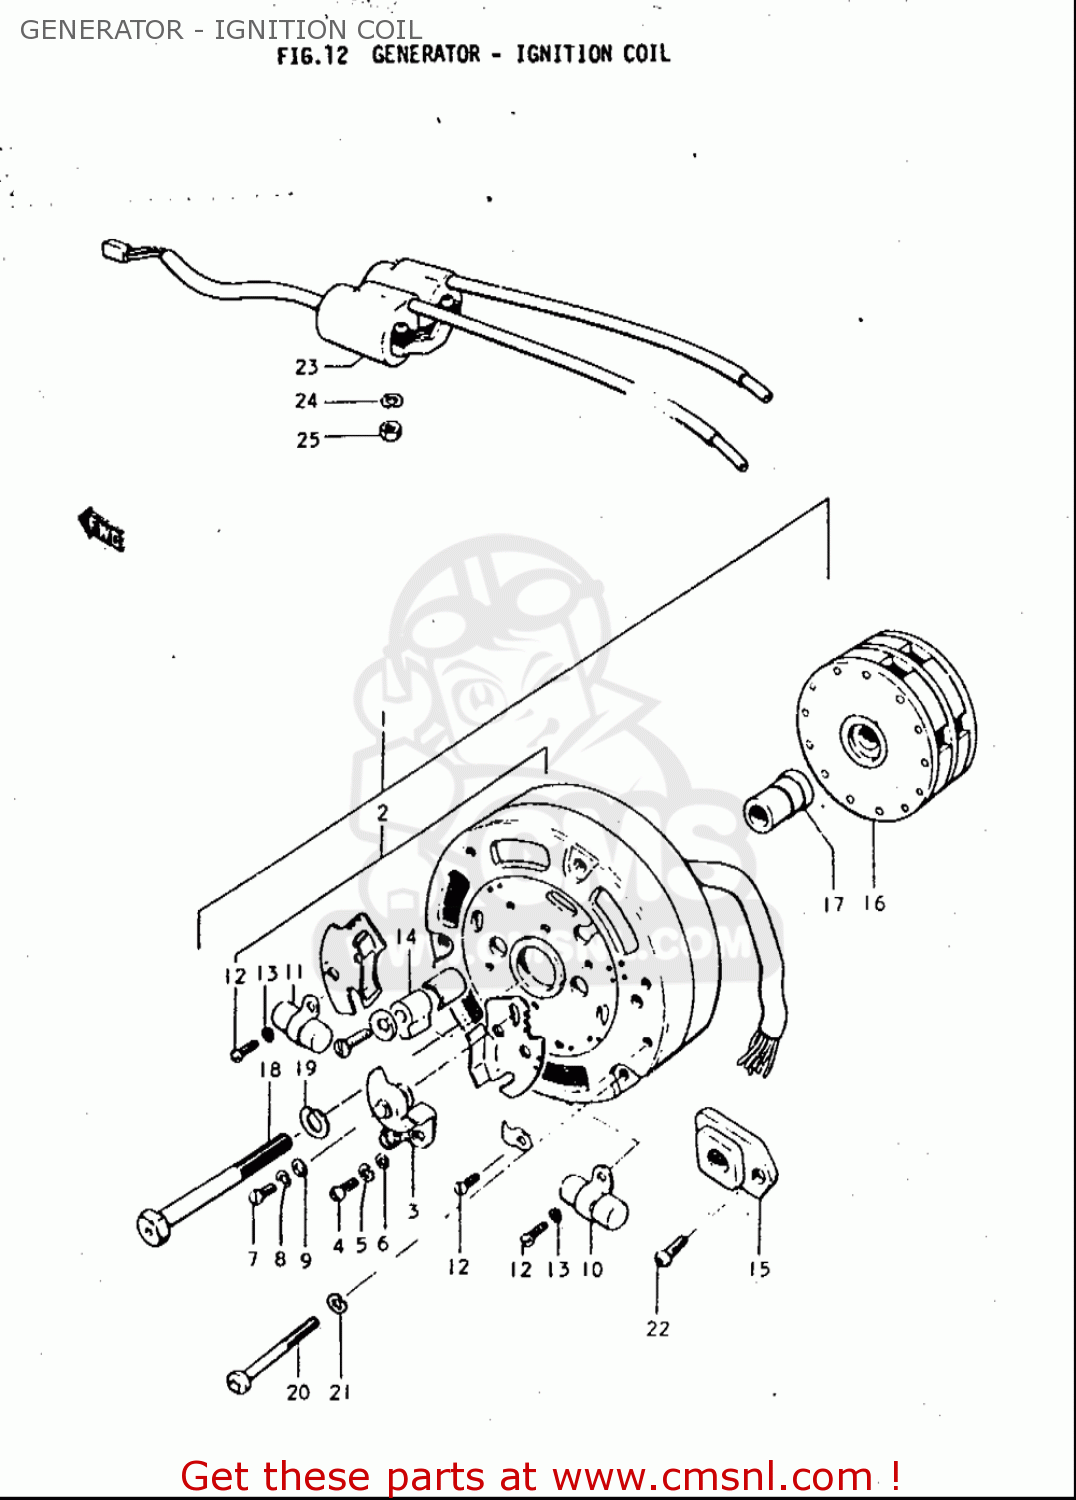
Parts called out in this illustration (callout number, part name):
3	POINT ASSY,CONTACT
4	SCREW(4X10)
5	WASHER,LOCK
6	WASHER
7	SCREW(4X10)
8	WASHER,LOCK
9	WASHER
10	CONDENSER,R
11	CONDENSER,L
13	WASHER,LOCK
14	.FELT, OIL
18	BOLT
19	WASHER,LOCK
20	SCREW
21	WASHER,LOCK
23	COIL ASSY,IGNITION
24	WASHER,LOCK
25	NUT
